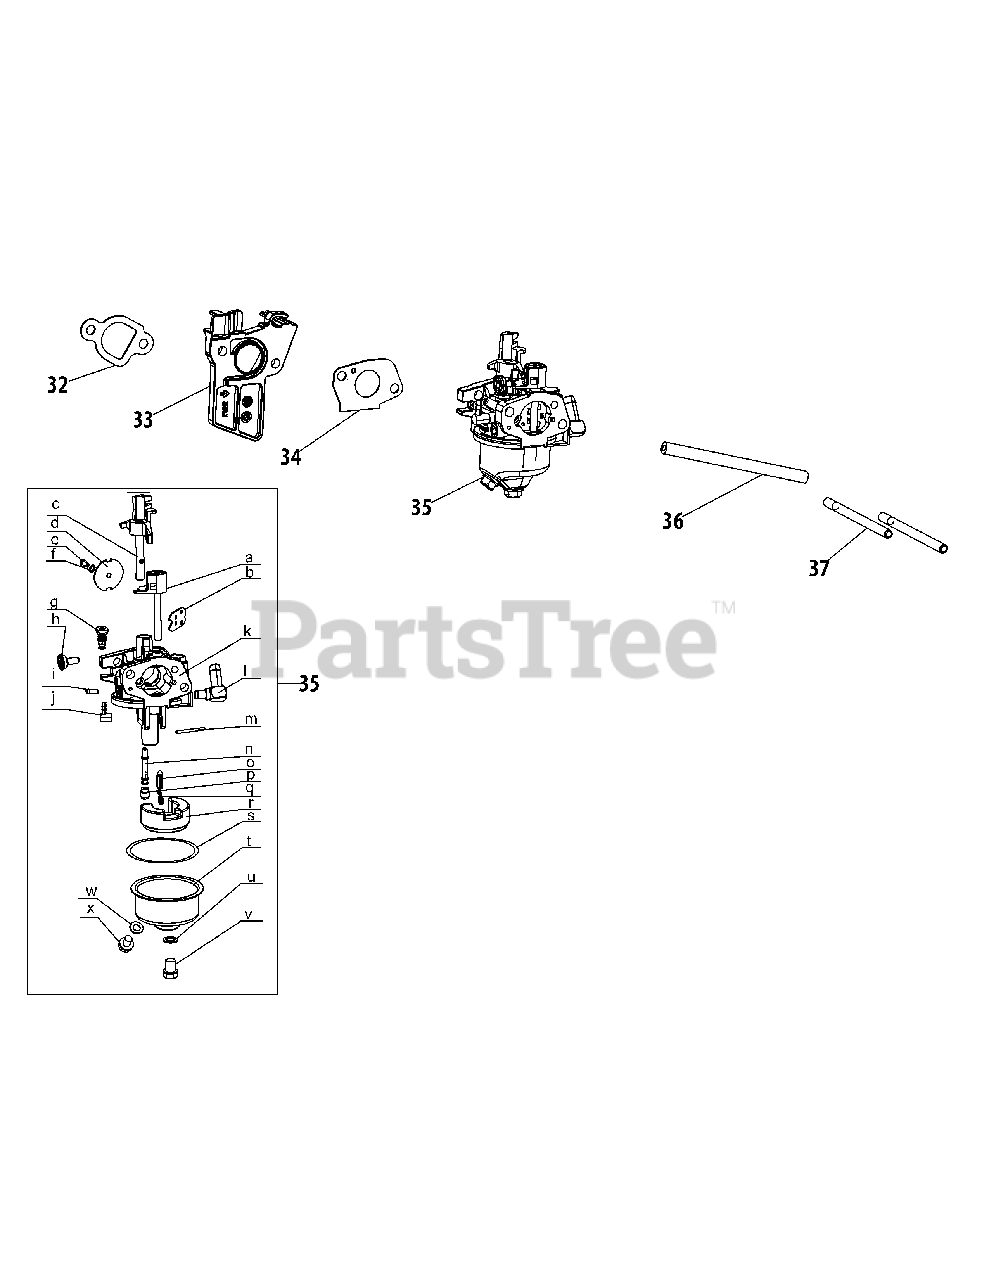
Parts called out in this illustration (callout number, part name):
32	Gasket, Carburetor Insulator
33	Insulator
34	Gasket, Carburetor
35	Carburetor
36	Fuel Hose,3.2×6.5×170
37	Stud, M6×92
